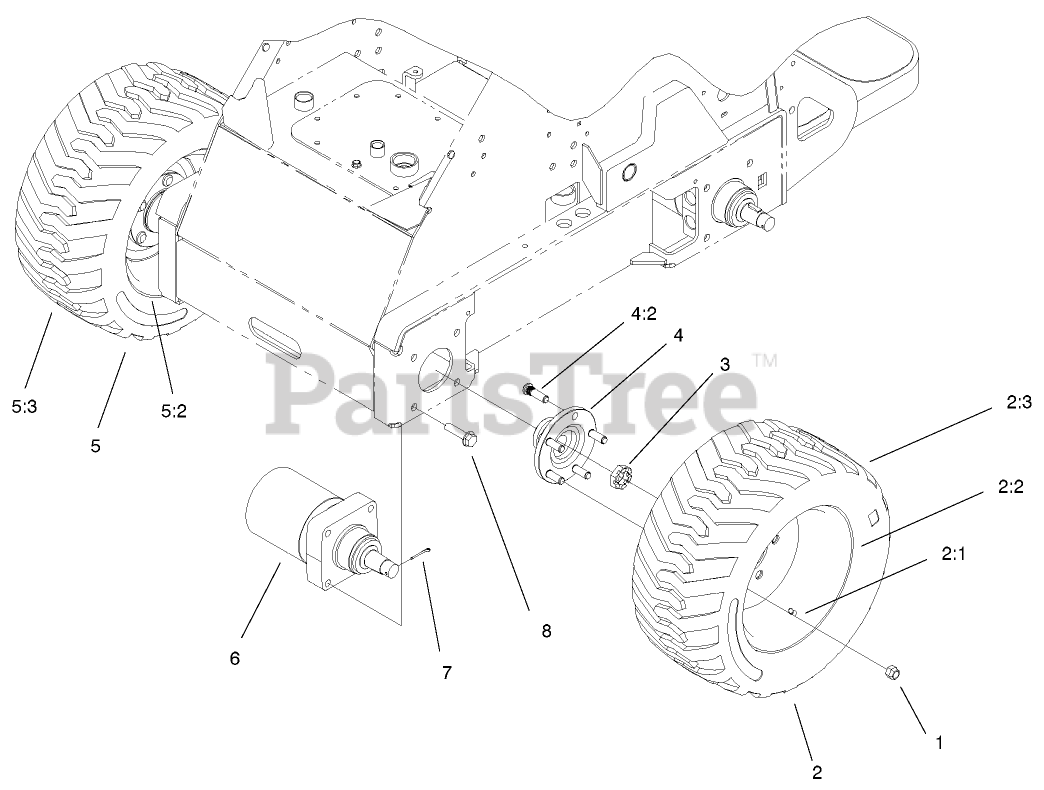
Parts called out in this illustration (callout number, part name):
1	NUT-LUG
2	LH WHEEL AND TIRE ASM
2:1	STEM-VALVE
2:2	WHEEL
4	HUB ASM
4:2	STUD-TYPE, DRIVE
5	RH WHEEL AND TIRE ASM
5:2	WHEEL
6	HYD MOTOR ASM
7	PIN-COTTER
8	SCREW-HHF
